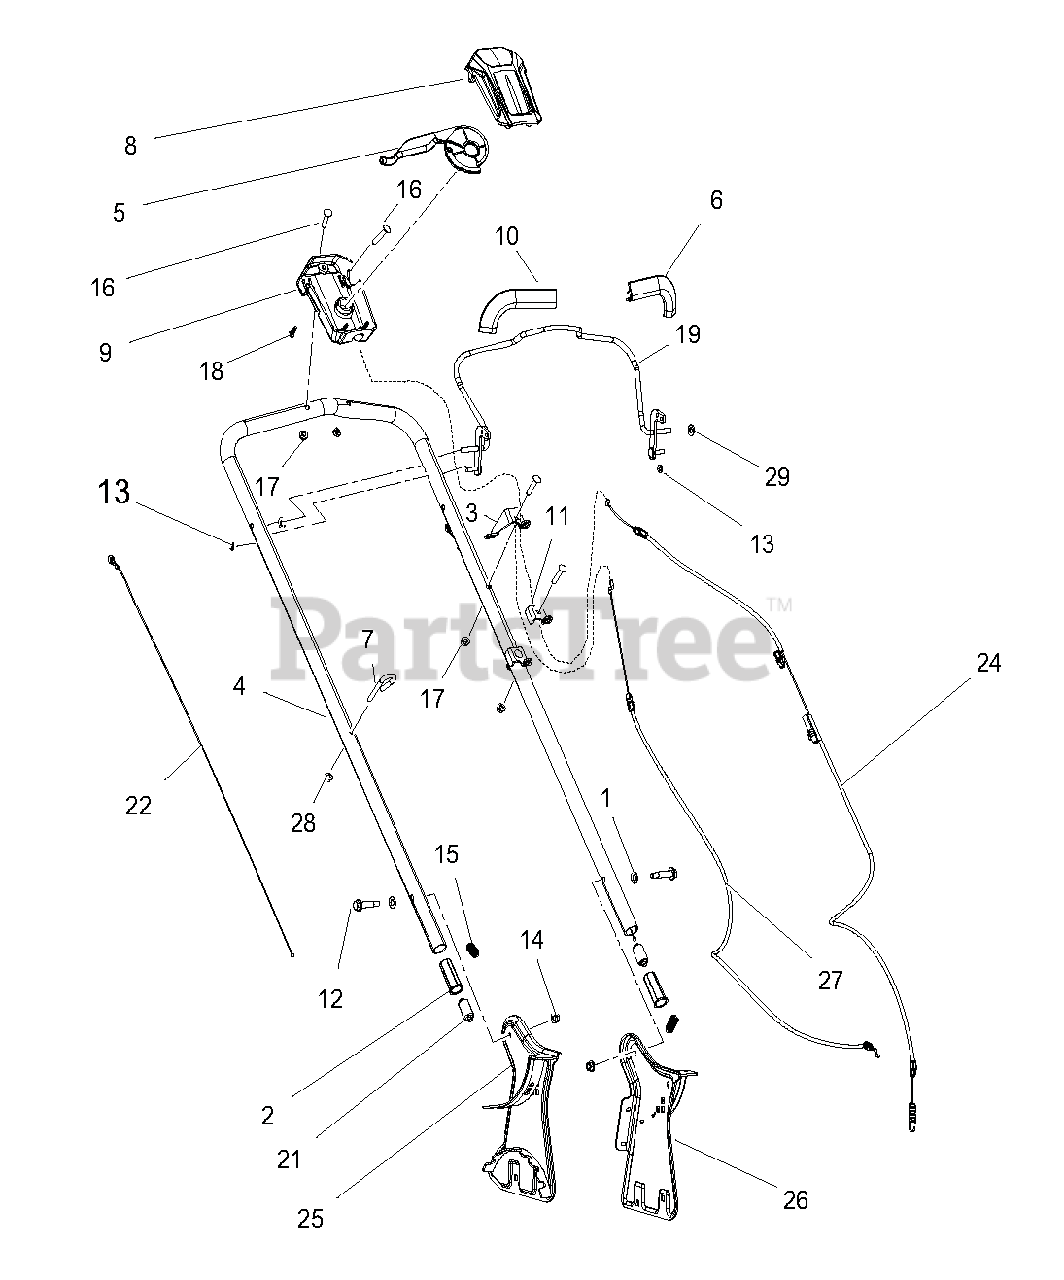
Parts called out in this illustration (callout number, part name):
1	WSHR,.385X.745X.030 STL YWZC
2	INSERT, HANDLEBAR ADJUST
3	BRKT, CABLE ANCHOR
4	HANDLEBAR, LM
5	HANDLE, DRIVE CONTROL
6	GUARD, FINGER - LH
7	HOLDER, RECOIL CORD
8	HOUSING, UPPER DRIVE CONTROL
9	HOUSING, LOWER DRIVE CONTROL
10	GUARD, FINGER - RH
11	BRKT, CABLE - DRIVE
12	BLT-SHLDR, .50X1.15X.312-18GR5
13	NUT-PUSH .25X.50 O.D.
14	@NUT-LK-TOP-FLG .31-18 YWZC
15	SPRING, COMPRESSION
16	@BLT-RDHDSQNK .25-20X1.50 G5YZ
17	@NUT-LK-TOP-FLG .25-20 YWZC
18	SCR-TAP 12-14X.75PLSTITE @BLZC
19	WLDMT, OPC BAIL
21	PLUNGER, HANDLEBAR LOCKING
22	CABLE, LM HANDLE ADJUST
24	CABLE, DRIVE CONTROL
25	SUPPORT, RH HANDLEBAR
26	SUPPORT, LH HANDLEBAR
27	CABLE, OPC
28	@NUT-LK-NYL-FLG .25-20 YWZC
29	@WSHR-FL-STL.344X.688X.065YWZC
